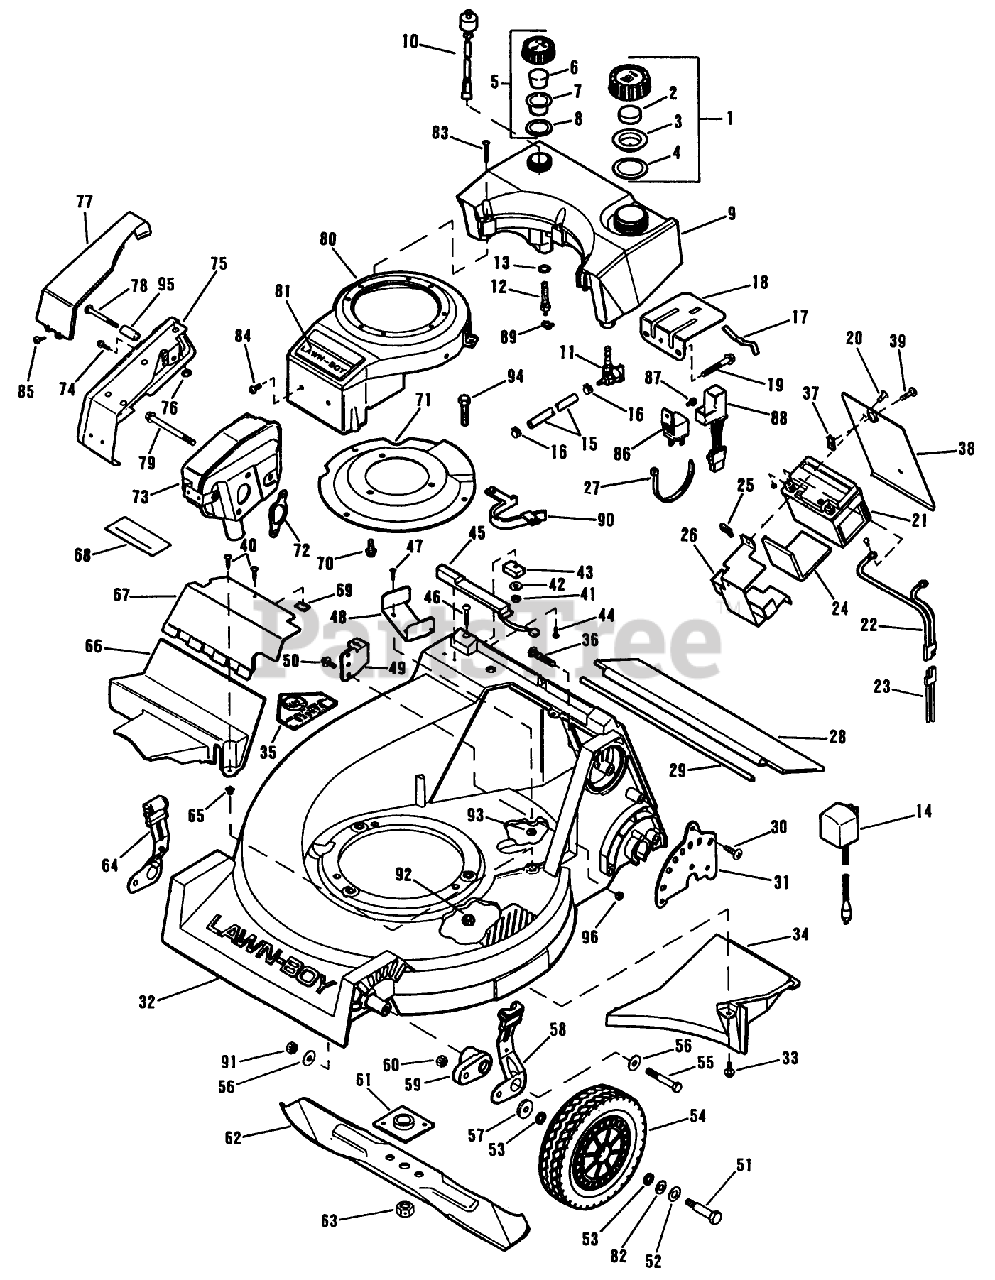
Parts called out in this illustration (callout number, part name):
1	CAP AY - FUEL M
2	BAFFLE - FOAM SM
4	GASKET-FUELCAP SM
5	CAP AY. OIL M
6	FILTER S
10	SWITCH AY-OIL S
11	DISC/LB SER.BUL.#6
15	GAS LINE SM
16	HOSE CLAMP SM
17	SPRING
18	DISC.LB SER.BUL.#6
19	SCREW-HEX W.H. SM
22	?Battery Wiring Harness
23	Wire Harness, Lower
25	SPEED NUT ARDEN
30	SCREW-BHTF
31	PLATE HGT CMS
34	CHUTE BAFFLE NYL
37	SPEED NUT LARSON
38	DOOR-ACCESS ELECT.
39	SCREW-CROSS RECESS
40	SCREW S
48	BELT GUIDELB
49	Cable Anchor
51	BOLT WHEEL QUAL
52	SPACER
53	WASHER
54	WHEEL&TIRE 8" TRI
56	WASHER-PLAIN
57	WASHER
58	KNOB & SPRING CMS
59	ARM HGT ADJ *BLACK
60	NUT-JAM, LOCKING
61	PLATE AND COLLAR ASM
63	NUT-BLADE
64	KNOB & SPRING CMS
65	NUT-CLIP
69	NUT-SPEED
71	PLATE SM
72	GASKET - EXH SM
74	SCREW S
75	MUFFLER GUARD AY
76	NUT-PUSH
77	COVER MUFFLER CP
78	SCREW SM
79	SCREW-SEMS
81	APPLIQUE SM
82	WASHER
83	DISC.LB SER.BUL.#6
85	SCREW SM
91	LOCKNUT
92	NUT-LOCK F
93	NUT C/LOCK E
94	SCREW-HH
95	SPACER S
96	LOCKNUT E
